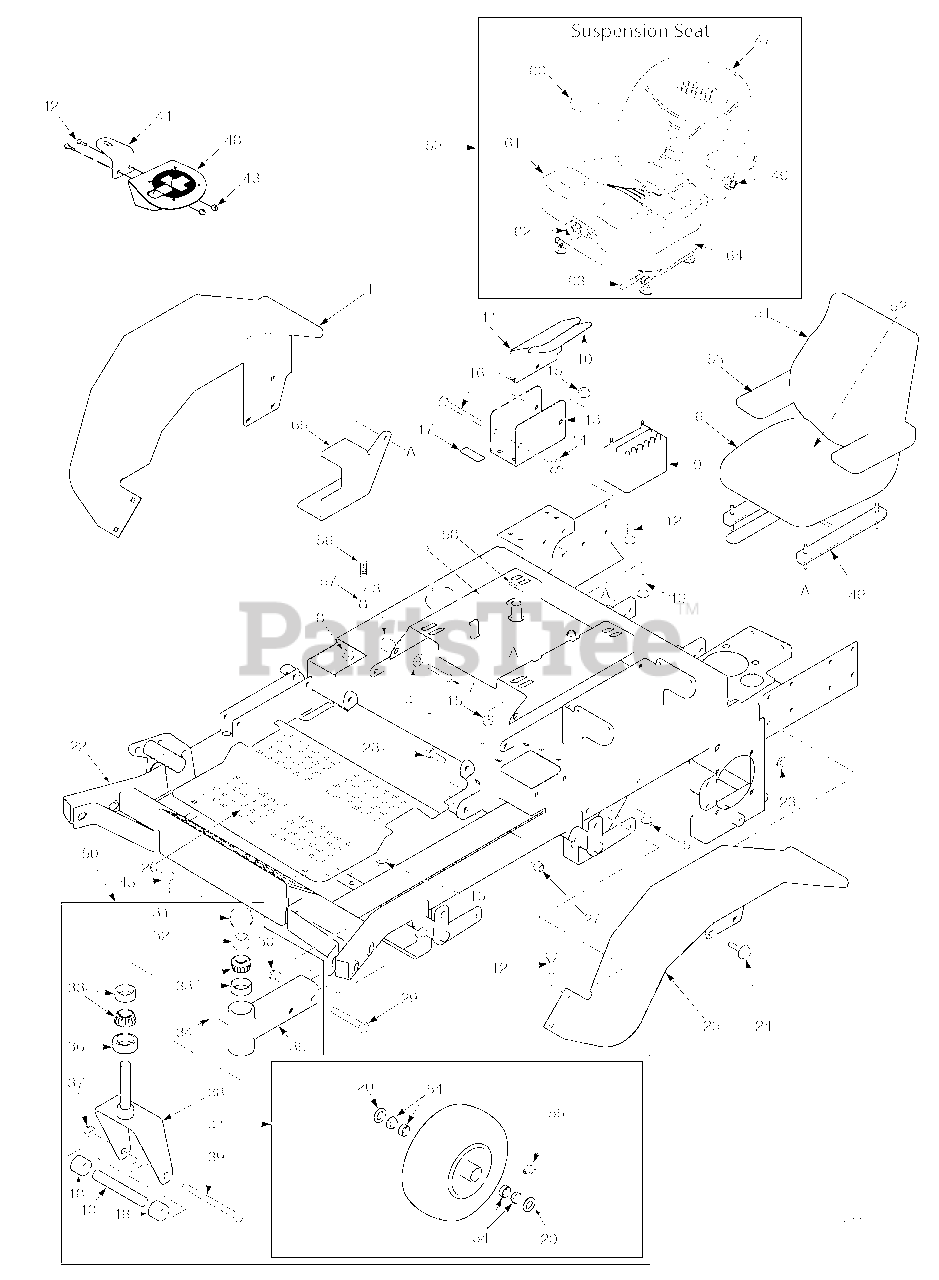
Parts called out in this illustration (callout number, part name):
1	Fender Weldment, RH
2	Bolt, Hex Head, 5/16-18 x 1, Zinc
3	Spacer
4	Flatwasher, 3/8 (.391 x .938 x .105")
5	Seat Plate Weldment
6	Seat Assembly w/Armrest and Seat Belt
7	Bolt, Hex Head 3/8-16 x 2.0"
8	Nut, Elastic Stop 3/8-16
9	Battery
10	Pad, Battery Cover
11	Cover, Battery
12	Bolt, Carriage 5/16-18 x 3/4"
13	Plate, Battery Box
14	Wing Nut, 1/4-20 x 3/4"
15	Nut, Hex Serrated Flange 5/16-18
16	Bolt, Carriage 1/4-20 x 6"
17	Rubber Pad
18	Spacer, Caster Wheel
19	Bolt, Carriage 5/16-18 x 1"
21	Locknut, 3/8-16, Elast. Stop
22	Main Frame
23	Nut, Hex Serrated Flange 3/8-16
24	Screw, Hex Serrated Flange 3/8-16 x 1"
25	Fender Weldment, LH
26	Foot Plate
27	Nut, Hex Elastic Stop 3/8-16
28	Bolt, Hex Head 3/8-16 x 1"
29	Bolt, Hex Head 5/8-11 x 4"
30	Nut, Hex Elastic Stop 5/8-11
31	Cap, Grease
32	Nut, Hex Elastic Stop 1.0-14
33	Bearing W/Race
34	Plug, 1/4-28 THD Form
35	Extention Weldment, Caster 52V (LH)
36	Seal, 2.00" OD. x 1.625" Bore
37	Nut, Hex Elastic Stop 1/2-13
38	Yoke Weldment, Caster
39	Bolt, Hex Head 1/2-13 x 7-1/2"
40	Sleeve, Caster Wheel
41	Wheel Assy, 52V
42	Bolt, Hex Head 1/4-20 x 3/4"
43	Bolt, Hex Head 1/4-20 x 3/4"
44	Mounting Bracket, STT Cup Holder
45	Lumbar Kit
46	Cable, Seat Stop
47	Back Cushion Kit
48	Cup Holder Assembly
49	Seat Adjustment, Track Set
50	Caster Wheel Assembly 52V (LH)
51	Back Cushion Cover
52	Seat Cushion Cover
53	Armrest, Right Hand
54	Bearing w/ Race
55	Grease Fitting
56	Spring, Seat
57	Pin Retainer, Spring
58	Roll Pin, Spring 5/32 x 3/4"
59	Suspension Seat Assembly w/seat belt
60	Armrest Only
61	Seat Cushion Kit Seat Drain Kit
62	Weight Adjustment Kit
63	Seat Adjustment, Track Set
64	Shock Absorber Kit
65	Guard, Fuel Line
